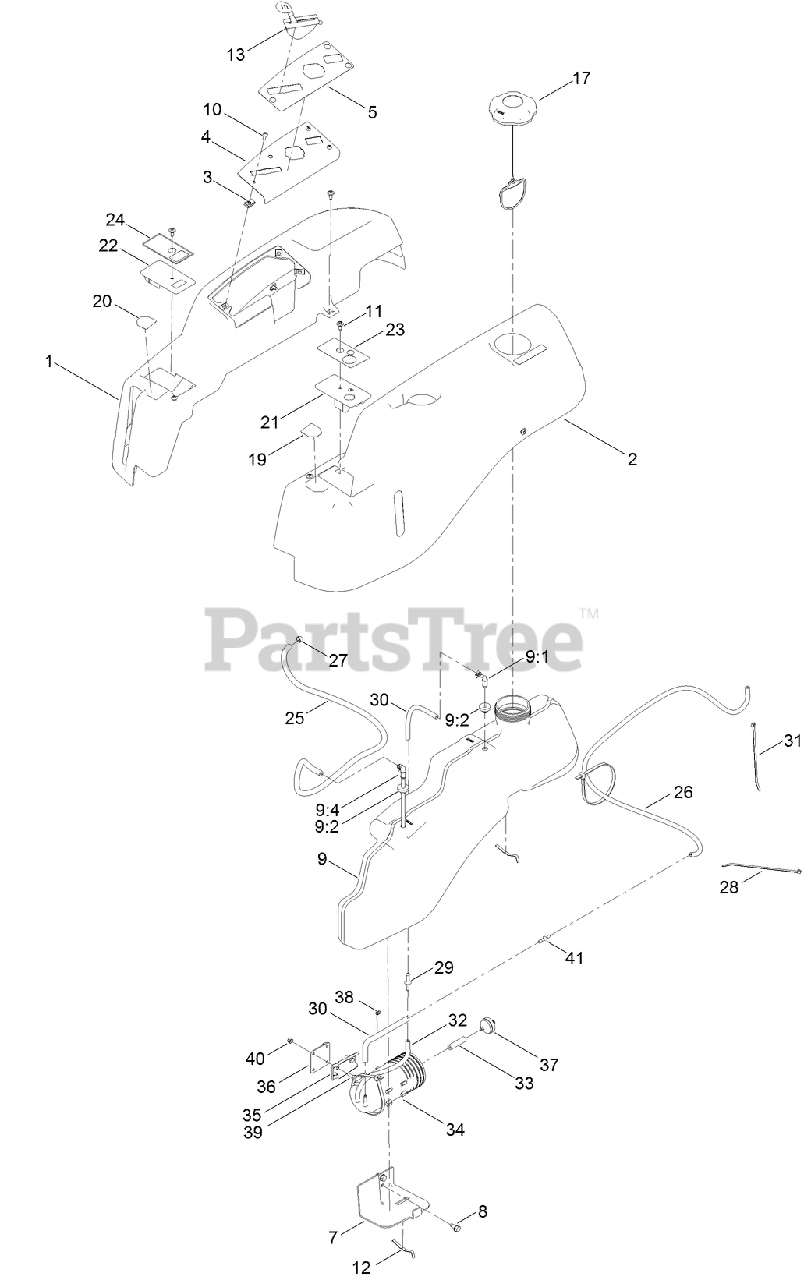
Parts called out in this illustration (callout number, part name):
1	POD-RH
4	PLATE-CONTROL
5	DECAL-PANEL, CONTROL
7	SUPPORT-TANK, FRONT
8	SCREW-HWHTF
9	FUEL TANK ASM
9:1	CONNECTOR-ELBOW, 90 DEG
9:2	BUSHING
9:4	FITTING-PLASTIC
10	SCREW-PRH
11	SCREW-SHOULDER
12	SPRING
13	CABLE-THROTTLE (45.0 IN)
19	DECAL-NMIR
20	DECAL-CONTROL, PEDAL
21	COVER-LH
22	COVER-RH
23	DECAL-KEYCHOICE
24	DECAL-BRAKE, PARKING
25	HOSE-FUEL
26	HOSE-FUEL
27	CLAMP-HOSE
28	TIE-CABLE
29	ADAPTOR-ORIFICE
30	HOSE-FUEL
31	TIE-CABLE
32	HOSE-FUEL
33	HOSE-FUEL
34	CANISTER-CARBON, 800CC
35	BRACKET-CANISTER, CARBON
36	PLATE-ADAPTER
37	FILTER-FUEL, INLINE
38	CARTRIDGE-VALVE, CHECK
39	SCREW-HH
40	NUT-LOCK, NI
41	FITTING-STRAIGHT
